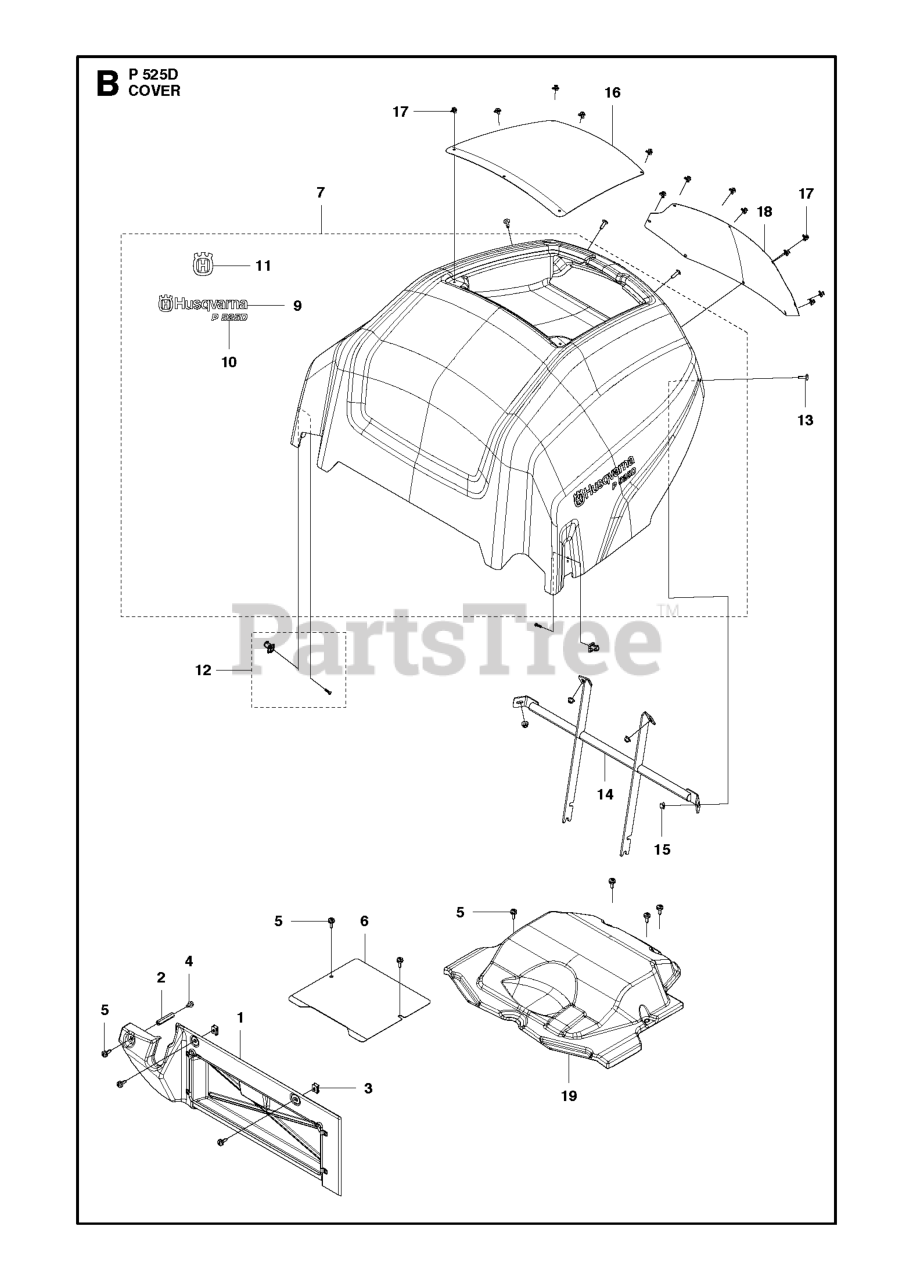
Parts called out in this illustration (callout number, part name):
9	DECAL.HUSQVARNA.210MM
11	DECAL HUSQVARNA CROWN HEIGHT 5
15	NUT FLANGE
